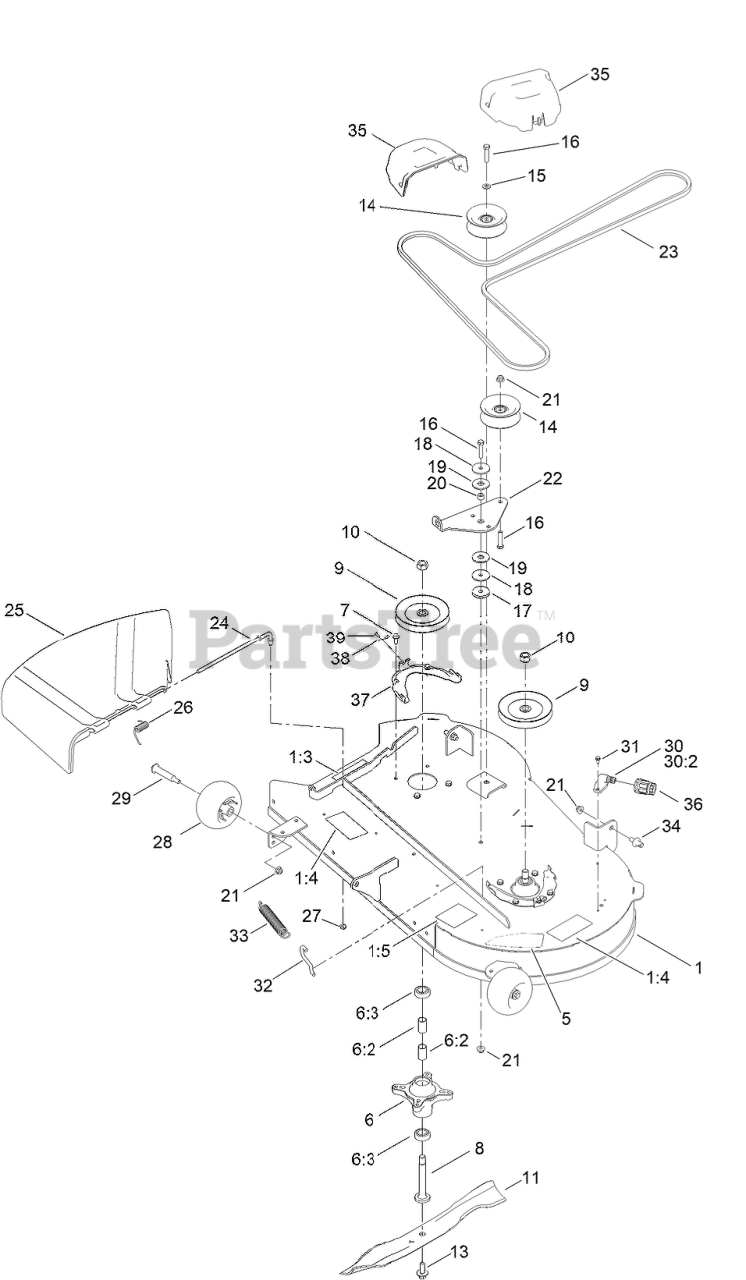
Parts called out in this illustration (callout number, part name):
1	42IN DECK AND DECAL ASM
1:3	DECAL-DANGER
1:4	DECAL-DANGER, DECK
1:5	DECAL-ROUTING, BELT
5	DECAL-DECK
6	SPINDLE ASM
6:2	SPACER
6:3	BEARING-BALL
7	SCREW-TAPTITE
8	SHAFT-SPINDLE
9	Pulley
10	NUT-HEX
11	BLADE-21.6 IN
13	BOLT-BLADE, SEMS
14	PULLEY-IDLER, FLAT
15	WASHER-FLAT
16	SCREW-HH
17	WASHER-PLAIN
18	WASHER-REBOUND
19	WASHER-FRICTION, COMPOSITE
20	SPACER
21	NUT-HF, NI
22	ARM-IDLER
23	V-BELT
24	ROD-PIVOT
25	DEFLECTOR-DISCHARGE
26	SPRING-TORSION
28	ROLLER-SCALP, ANTI
29	BOLT-SHOULDER
30	FITTING-WASHOUT
30:2	O-RING
31	SCREW-HWH
32	HOOK-RETURN SPRING
33	SPRING-EXTENSION
34	PIN-DECK
35	COVER-BELT
36	CONNECTOR-HOSE
37	BRACKET-COVER, BELT
38	PIN-HAIR
39	SCREW
